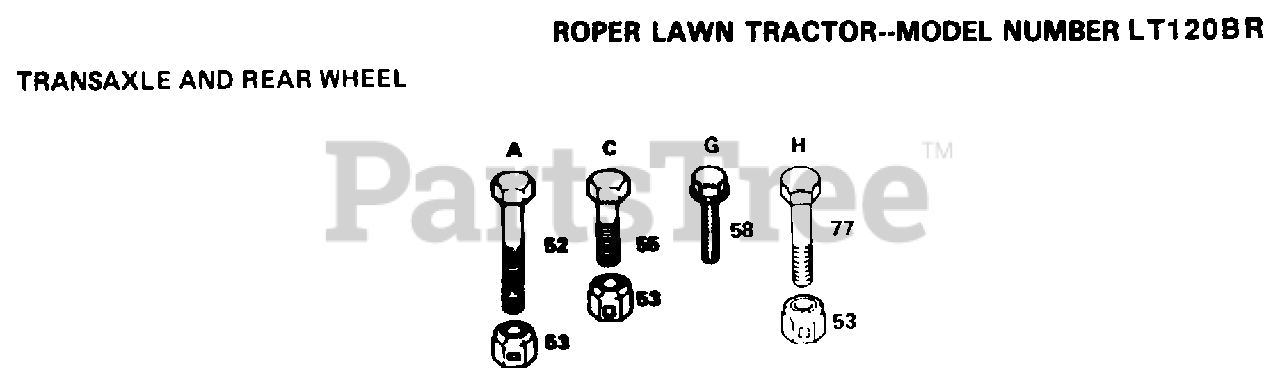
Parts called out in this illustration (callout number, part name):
52	BOLT
58	SCREW
77	BOLT
